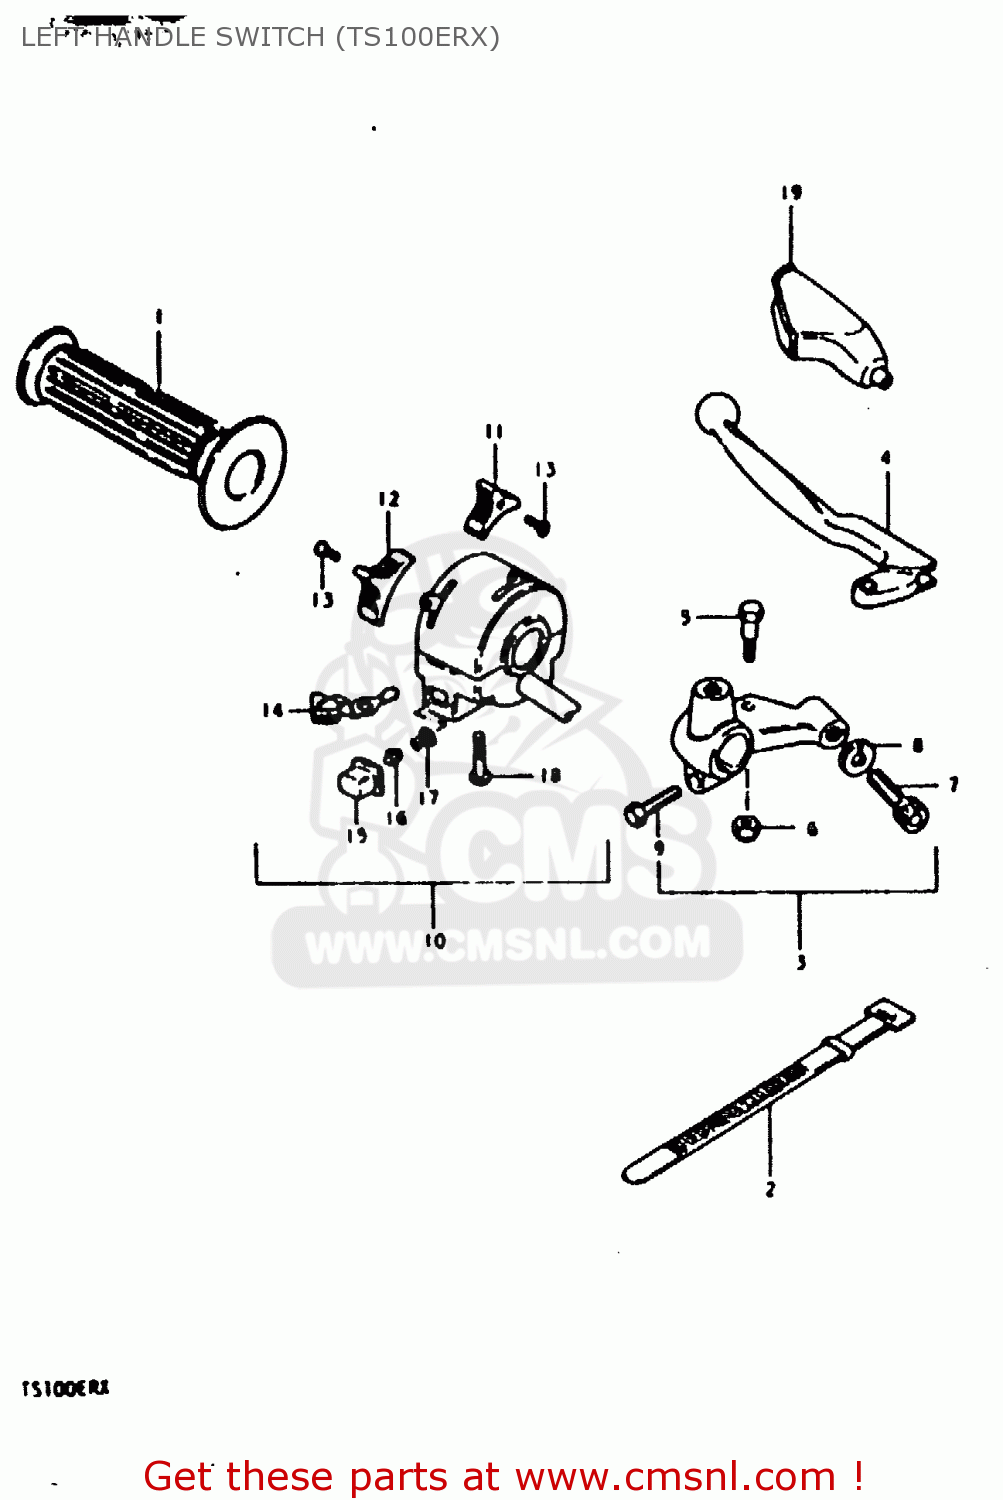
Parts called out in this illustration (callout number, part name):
1	GRIP,L
2	CLAMP(L:120)
3	LEVER ASSY,CLUTCH
4	LEVER,CLUTCH
5	BOLT,LEVER
6	NUT 6MM
7	ADJUSTER,CABLE
8	NUT,CABLE ADJUSTER
9	BOLT
10	SWITCH ASSY,HANDLE,L
11	KNOB,LIGHTING SWITCH
12	KNOB,DIMMER SWITCH
13	SCREW
14	KNOB,TURNSIGNAL
15	BUTTON,HORN
16	CONTACT
17	SPRING
18	SCREW
19	COVER,CLUTCH LEVER
